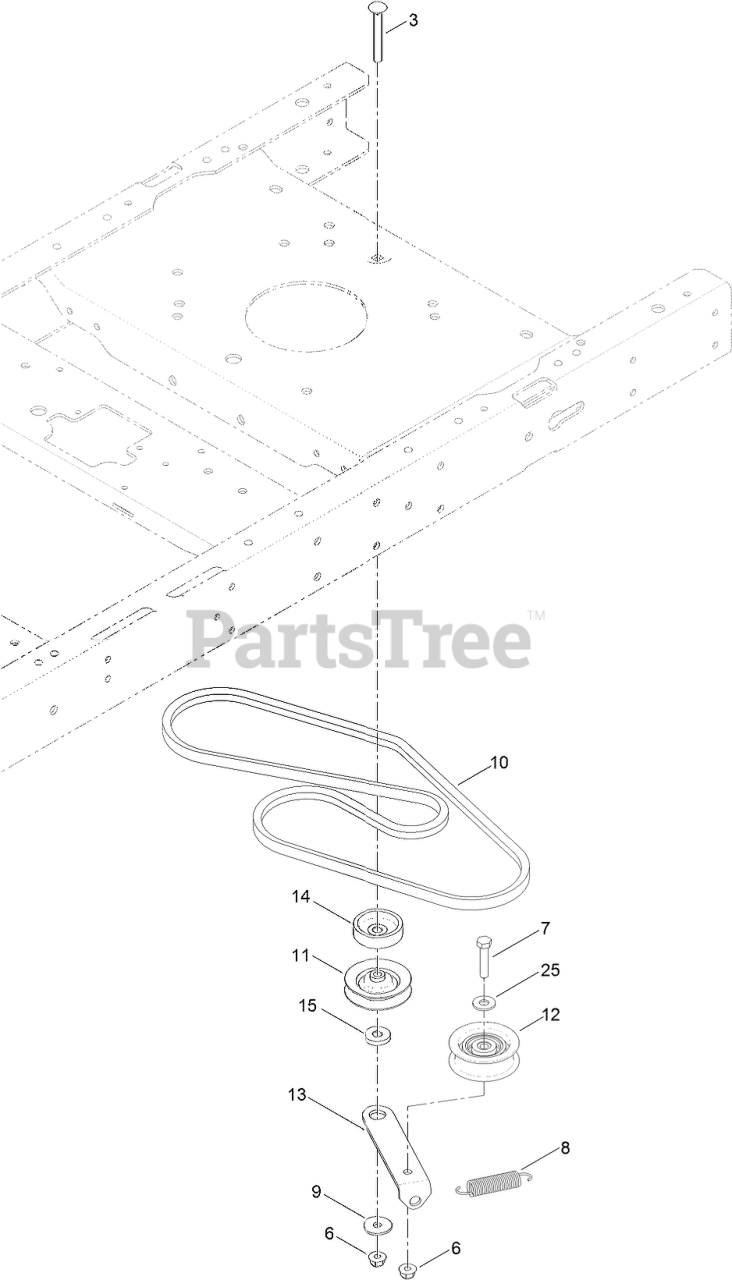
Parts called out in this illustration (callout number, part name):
3	SCREW-CARR
6	NUT-HF, NI
7	SCREW-HH
8	SPRING-RETURN, PEDAL
9	WASHER-PIVOT
10	V-BELT
11	PULLEY-IDLER
12	PULLEY-IDLER
13	ARM-IDLER
14	SPACER
15	SPACER-ARM, IDLER
25	WASHER-FLAT
